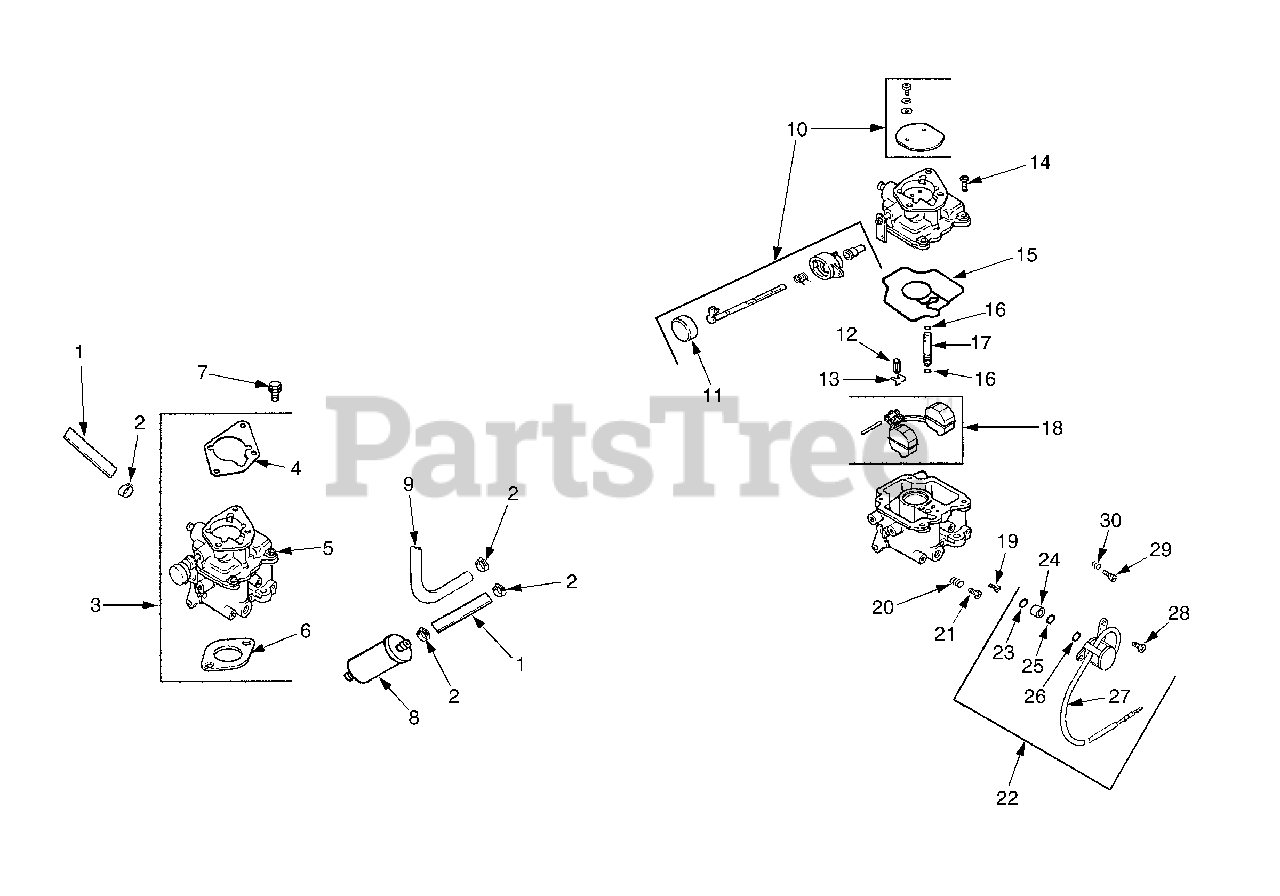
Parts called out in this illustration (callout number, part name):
1	Line, Fuel 10"
2	Clamp, Hose
3	Kit, Carburetor w/Gasket
4	Gasket, Air Cleaner Base
5	Carburetor Assembly
6	Gasket, Carburetor
7	Screw, Hex Flange
8	Filter, Fuel
9	Line, Fuel 11"
10	Kit, Choke Repair
11	Cap, Choke Lever
12	Clip, Inlet Needle Value
13	Valve, Inlet Needle
14	Screw, Carburetor Body
15	Gasket, Carburetor Body
16	O-Ring Slow Jet
18	Kit, Float Repair
20	Spring, Idle Adjust Screw
21	Screw, Idle Adjusting
22	Kit, Solenoid
24	Seat, Solenoid
27	Solenoid
28	Screw, Solenoid
29	Needle, Idle
30	Spring, Idle Needle
